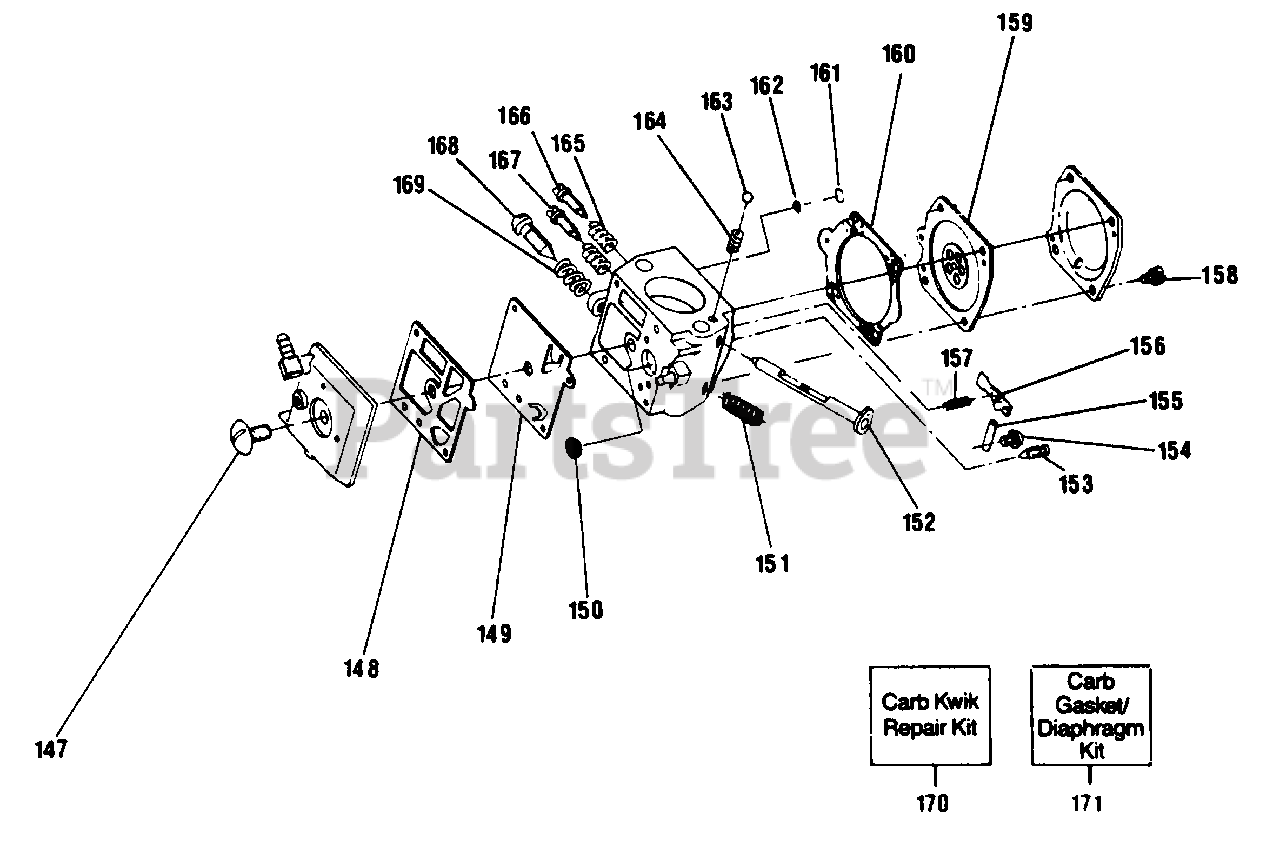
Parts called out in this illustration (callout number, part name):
148	Fuel Pump Gasket
149	Fuel Pump Diaphragm
150	Inlet Screen
151	Throttle Spring
152	Choke Shaft & Lever Ass'y.
153	Inlet Needle Valve
154	Screw
155	Pin
156	Metering Lever
157	Spring
159	Metering Diaphragm
160	Metering Diaphragm Gasket
161	Retaining Ring
162	Check Valve Screen
164	Spring
165	Needle Adjusting Spring
166	High Speed Needle
167	Idle Needle
168	Idle Adjust Screw
169	Idle Adjust Spring
170	Kwik Repair Kit
171	Carb. Gasket Kit
